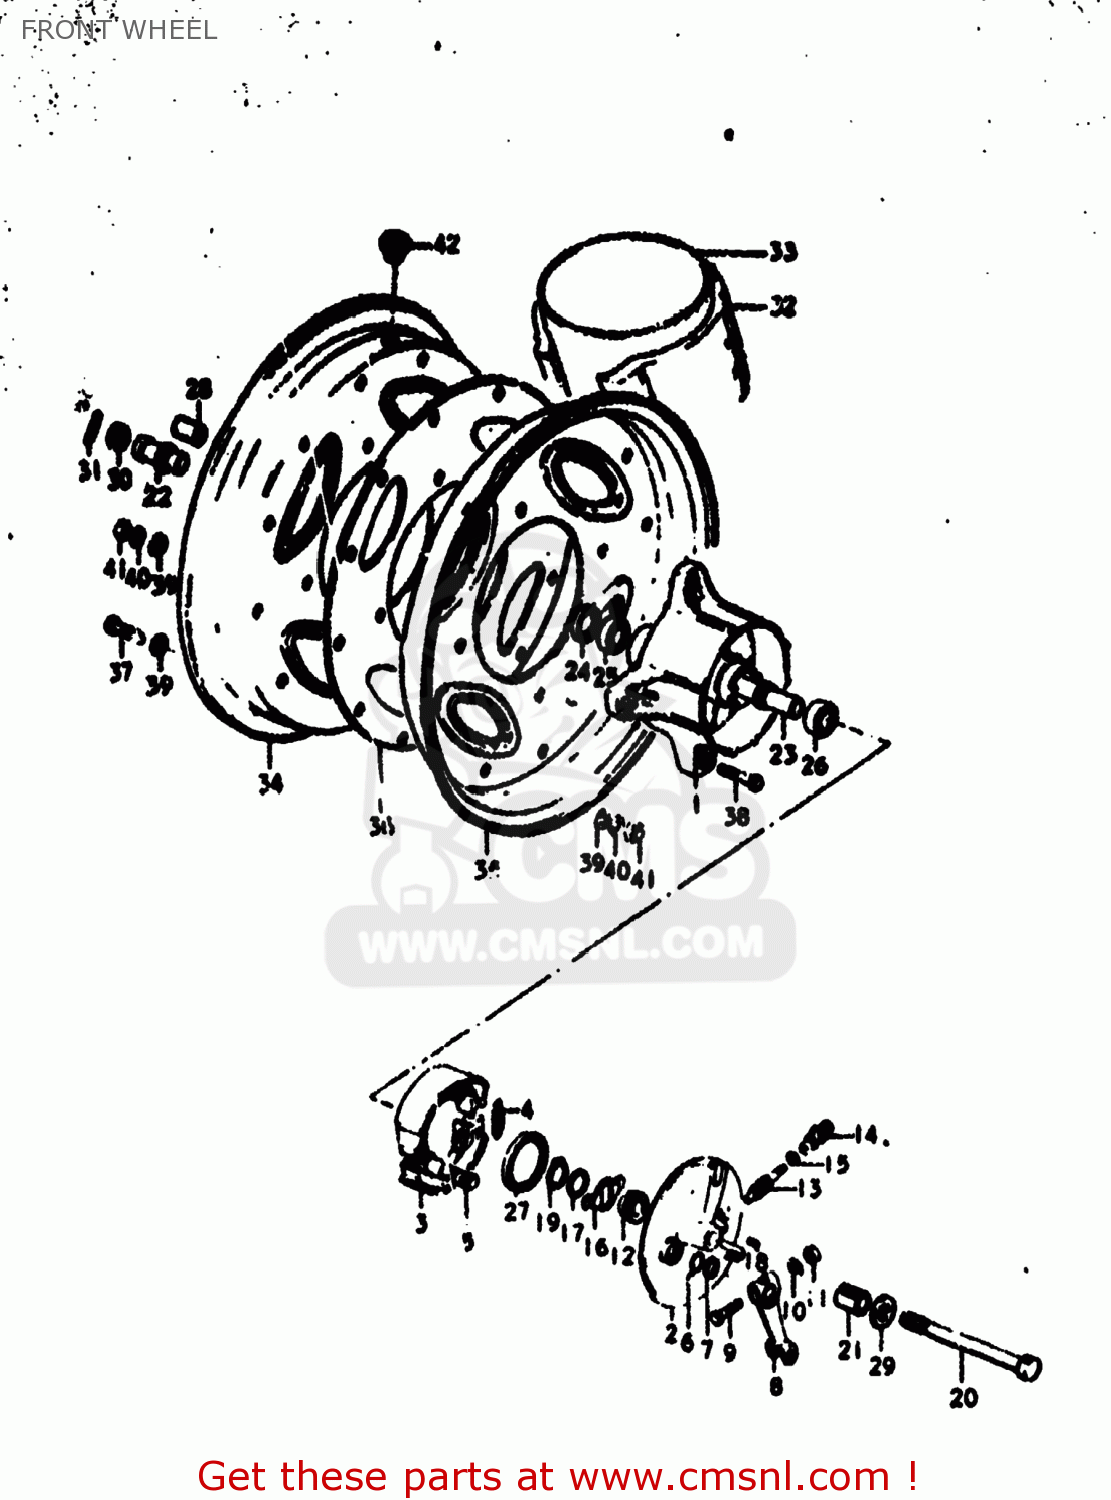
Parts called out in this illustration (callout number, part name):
1	HUB,FRONT
2	PANEL,FRONT HUB
3	SHOE,BRAKE
4	SPRING(L:34)
5	CAM,FRONT BRAKE
6	O RING(D:2.5,ID:11.4)
7	WASHER(12.5X20X1)
8	LEVER,FRONT BRAKE CAM
9	BOLT
10	WASHER
11	NUT
12	GEAR,SPEEDOMETER
13	PINION,SPEEDOMETER
14	BUSH,METER GEAR OUTER
15	WASHER (5.1X9X0.4)
16	DRIVER,SPEEDOMETER GEAR
17	WASHER(18.5X24X1)
18	SCREW
19	CIRCLIP
20	AXLE,FRONT
21	SPACER (12X20X41)
22	SPACER,FRONT AXLE,RIGHT
23	SPACER,FRONT HUB BEARING
24	SEAL,OIL(18X32X7)
25	BEARING
26	BEARING, LH
27	OIL SEAL
28	SPACER (12X20X44)
29	WASHER
30	NUT 12MM
31	COTTER PIN
32	TIRE,FR
33	TUBE,INNER
34	RIM,WHEEL
35	RIM,WHEEL,OUTER
37	BOLT
38	BOLT
39	WASHER
40	LOCK WASHER
41	NUT
42	BUSHING
